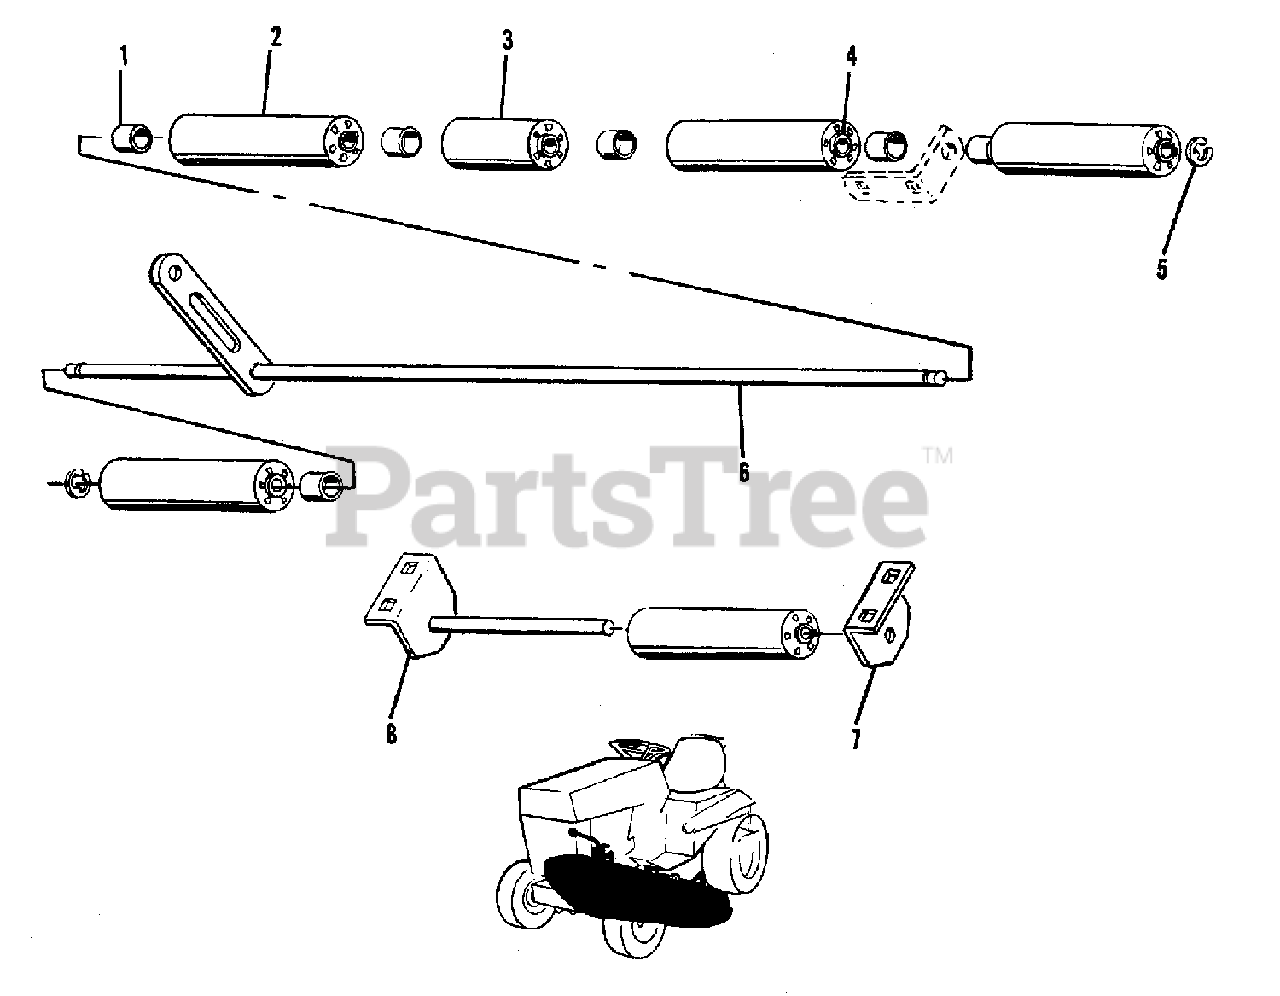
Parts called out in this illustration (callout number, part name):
1	SPACER, .66 ID
2	ROLLER ASSEMBLY, Long (Include BUSHING - Order as Required)
3	ROLLER ASSEMBLY, Short (Include BUSHING - Order as Required)
4	BUSHING, Roller
5	RING, Retaining (Use Only On Shaft Without Cotter Pins)
6	SHAFT ASSEMBLY, (Retaining Ring Type)
6	SHAFT ASSEMBLY, 48" Mower (Cotter Pin Type)
6	SHAFT ASSEMBLY, 42" Mower (Cotter Pin Type)
6	PING, 3/16 x 1, Cotter
7	BRACKET, Center Roller
7	CARRIAGE BOLT, 5/16NC x 3/4
7	LOCKWASHER, 5/16
7	NUT, 5/16NC
8	SHAFT ASSEMBLY, Center Roller
8	CARRIAGE BOLT, 5/16NC x 3/4
8	LOCKWASHER, 5/16
8	NUT, 5/16NC
